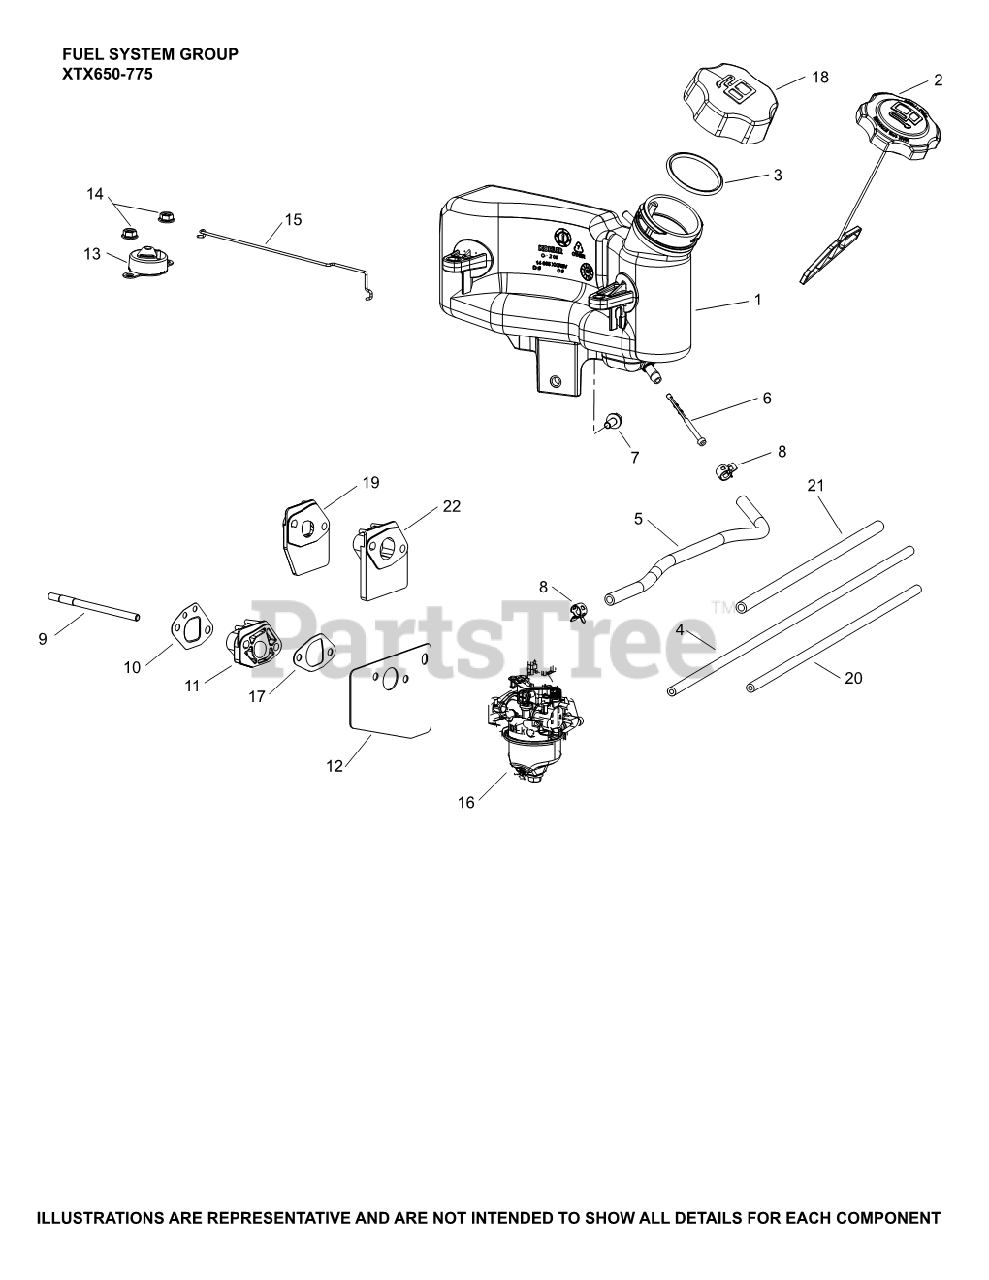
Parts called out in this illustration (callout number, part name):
1	TANK, FUEL
2	CAP ASSEMBLY, FUEL
3	SEAL, FUEL CAP
6	FILTER, FUEL IN-NIPPLE
8	CLAMP, HOSE (NON-CALIFORNIA) - USE 14 237 10-S
9	STUD,M6X1.0X100.2MM
12	KIT, CARBURETOR HEAT SHIELD GASKET
16	KIIT, CARBURETOR 13 MM STD CHOKE
17	KIT, INTAKE GASKET
20	HOSE, EVAPORATIVE
21	HOSE, FUEL LOW-PERMEATION
22	KIT, SPACER
